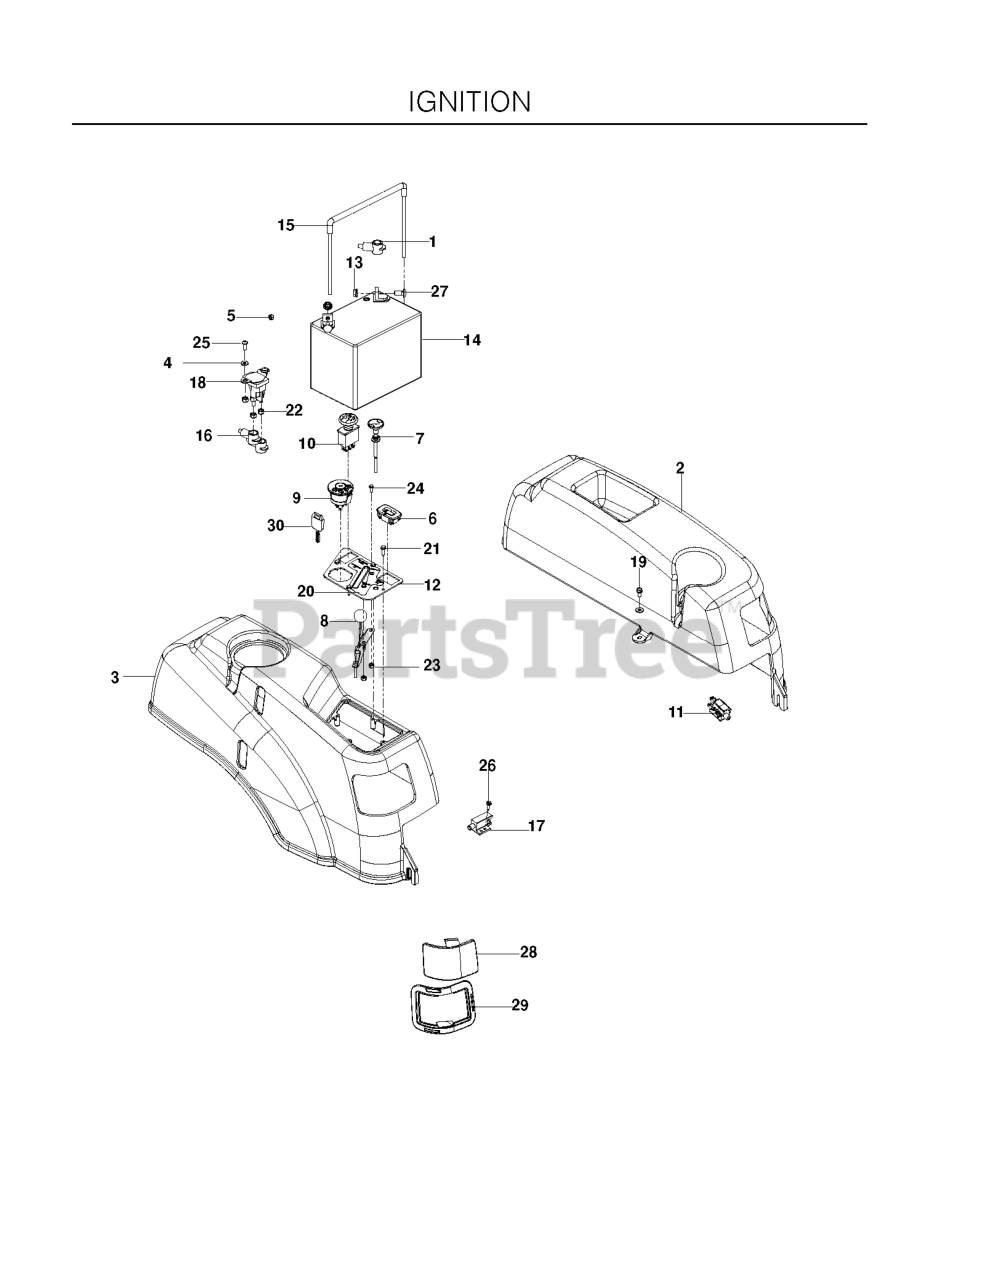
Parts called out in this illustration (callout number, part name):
1	TUBE.HANDLE.BAGGER.CRD/SRD.BLA
2	FENDER, LT
3	NUT T
3	FENDER, RT, GRAY
4	HANDLE.BAGGER.W/LVRS.BLK.CRD
4	WASHER 1/4 INT TOOTH
5	SCREW.PAN.HEAD
5	JAM NUT 1/4C (2 2 PW01)
6	REPL BY 532 75 00-29
6	HOUR METER
7	CHOKE CABLE
8	COVER.PNT.BGR.CRD.WSLOTS.MS668
8	THROTTLE CABLE
9	Bolt Carriage 1/4-20 x 2.25d x Gr.5
9	RP IGNITION SWITCH
10	TUBE
10	RP.SWITCH, BLADE
11	BRACKET.SUPPORT.UPPER.BAG.CRD
11	SWITCH, BRAKE 3P
12	BRKT PIVOT
12	CONSOLE.PLATE.BLACK
13	5/16-18 NYLOC FLANGE NUT
14	BOLT-HEX EAK
14	BATTERY, 12 V 330 AMP
15	RETAINER-SPRNG RB
15	BATTERY TIE DOWN ASSEMBLY
16	NUT LOCK FLG 3/8-16 UNC
16	TERMINAL COVER-SM
17	RP BOLT 5/16-18 X3/4 ZN/YEL GR
17	SWITCH, INTERLOCK
19	NUT LOCK HEX FLANGE 5/16-18
19	BOLT 1/4-20 X 1/2 HWST
20	BRKT.PIVOT.RH.CRD
20	DECAL, CTRL PANEL, HUSQ
21	BAGGER.ASM.CRD.2007
21	HCS #10-24 X 1/2
22	BRACKET.BAGGER.SD.ELECTRIC.CRD
22	NUT.1/4-20.HEX.NYLOC.ZD
23	NUT 10-24 NYLOC
24	TUBE.PIVOT.BAG.CRD.BLACK
24	SCR #10-12X3/4 HEX WAS HD ZD
25	PIPE
25	SCR 1/4-20 X 5/8 BTN SKT HD ZD
26	SCREW #10 X 1/2 SELF TAPPING
27	BOLT 5/16C X 3/4" CARRIAGE
28	GRIP.HANDLE.BLACK
28	LENS, COLORED LEFT
29	LEFT HEADLIGHT RIM GREY
30	KEY
31	RETAINER CLIP
32	RIVET,DRILLED
33	MULCHING.PLUG.107.CRD.(2 2)
34	HANDLE.MULCHER.92.CRD (2 2)
36	WASHER
37	PLUG PLUG.SUPPORT.BAGGER.CRD
38	BOLT.5/16-18X2.5
39	SEAL.BAGGER.CRD
41	BRACKET.BAGGER.SD.ELECTRIC.CRD
43	PLUG, TUBING END
46	BOLT.CARRIAGE.5/16-18
47	PIPE
49	ROD
50	NUT.71038.31-18.HEX.NYLOCK
51	LATCH
53	NUT
54	BOLT
69	WASHER
70	RIVET RIVET POP
